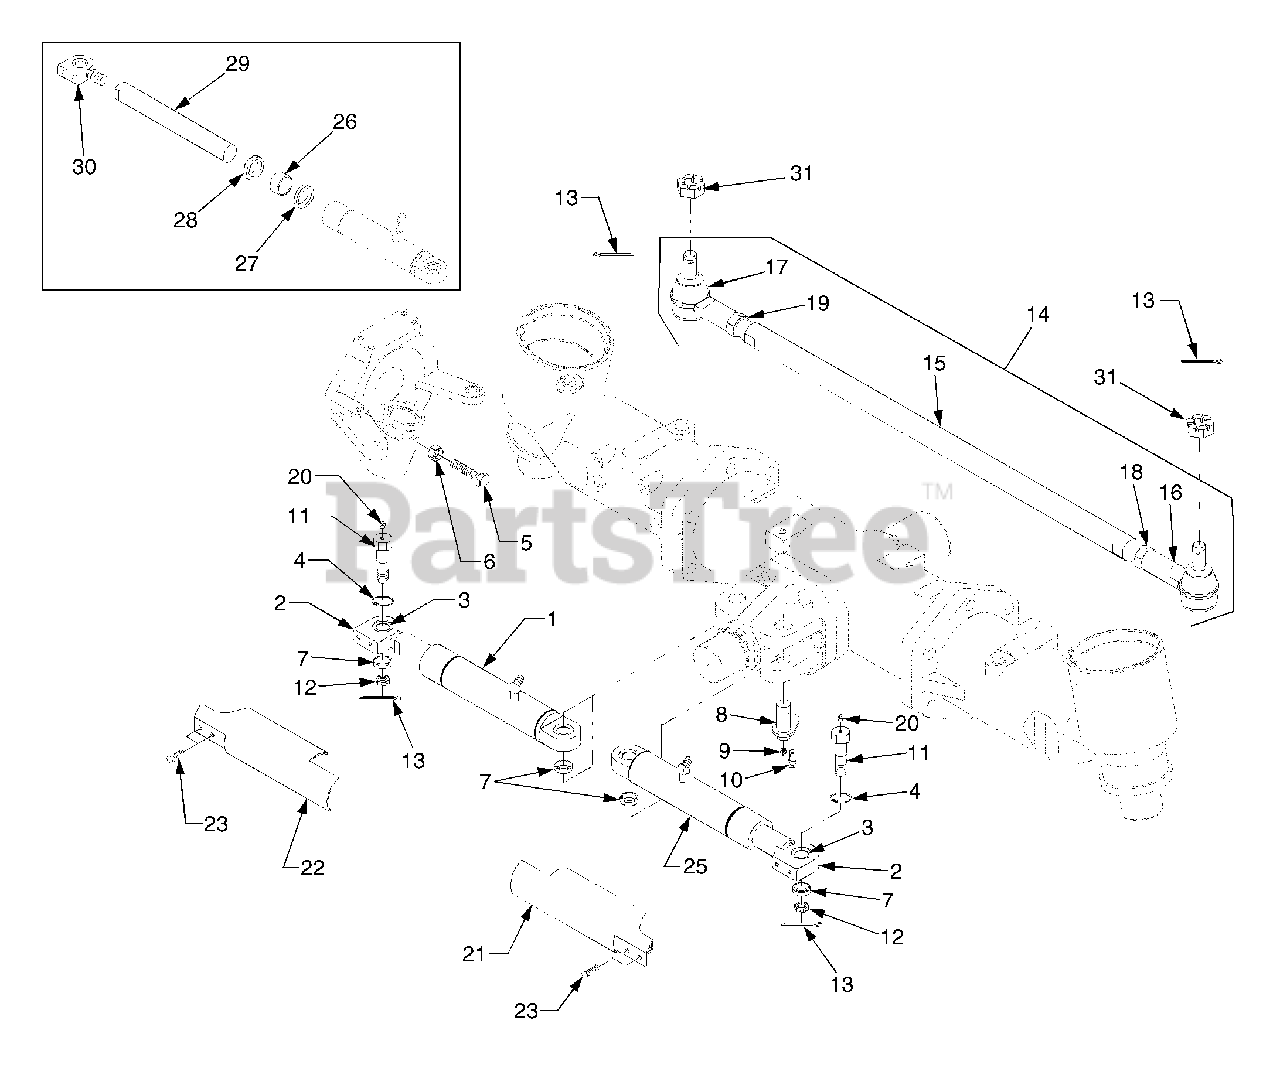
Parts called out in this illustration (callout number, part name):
1	Steering Cylinder Ass'y RH
8	Pin, Cylinder Support
14	Tie Rod Ass'y
16	Tie Rod End Ass'y (LH)
17	Tie Rod End Ass'y 2 (RH)
21	Cover, Cylinder (LH)
22	Cover, Cylinder (RH)
25	Steering Cylinder Ass'y. LH
